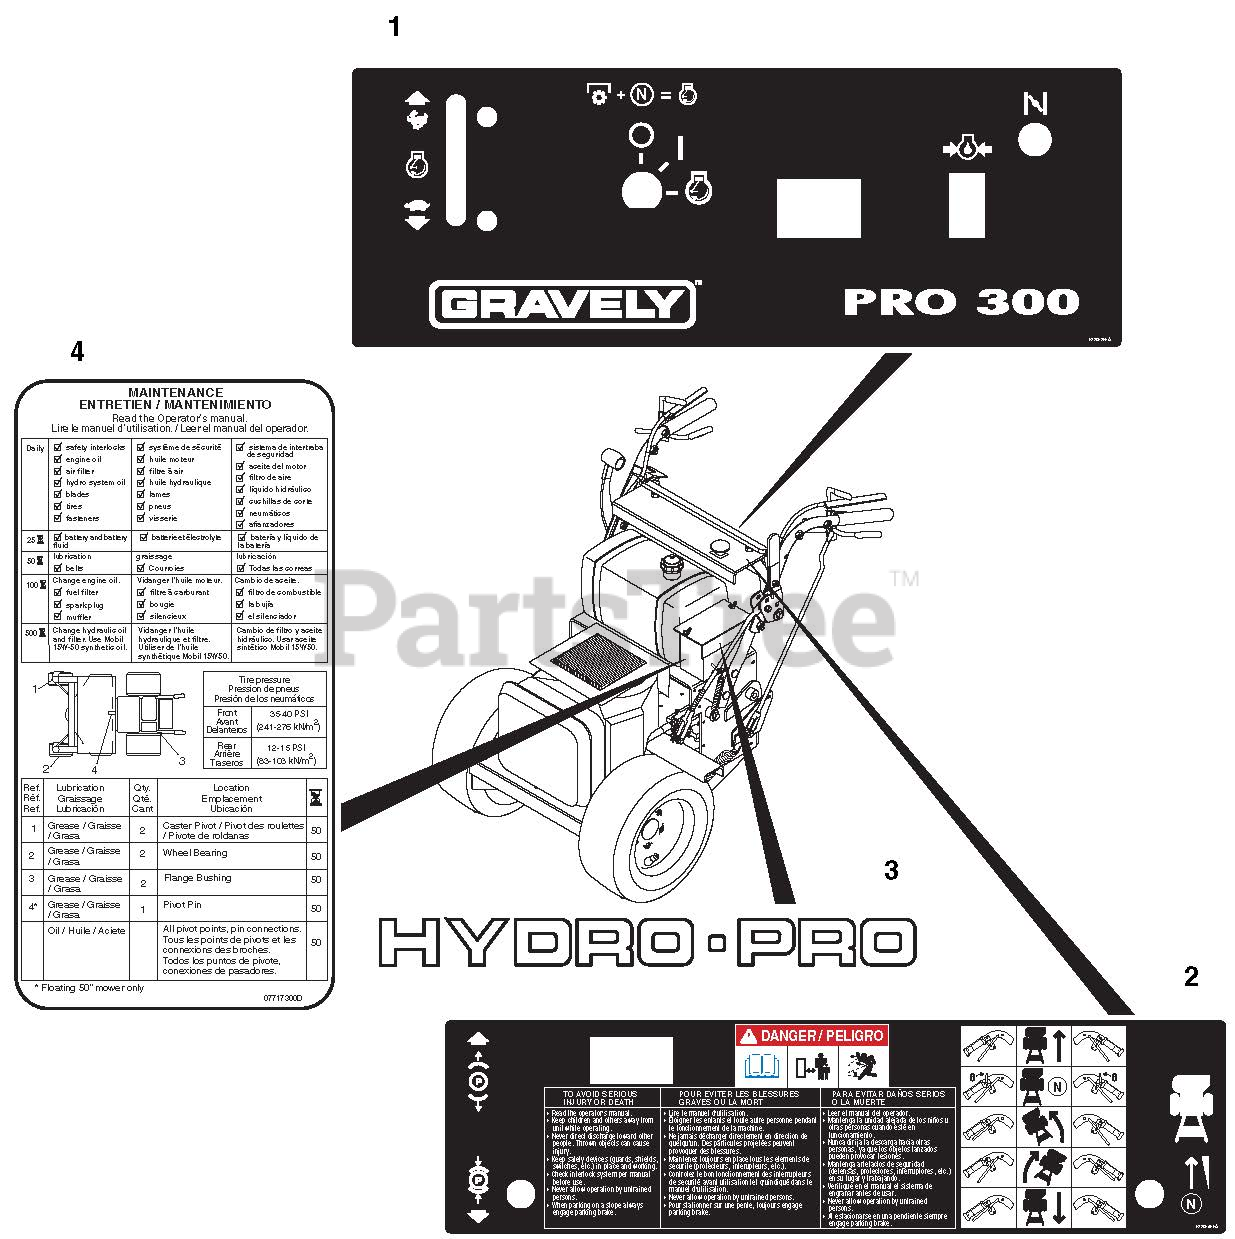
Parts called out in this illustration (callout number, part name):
1	Decal, Pro 300 Instrument Panel
2	Decal, Pro-300 Dash
3	Decal, Hydro Pro
4	Decal, Pro 300 Maintenance
